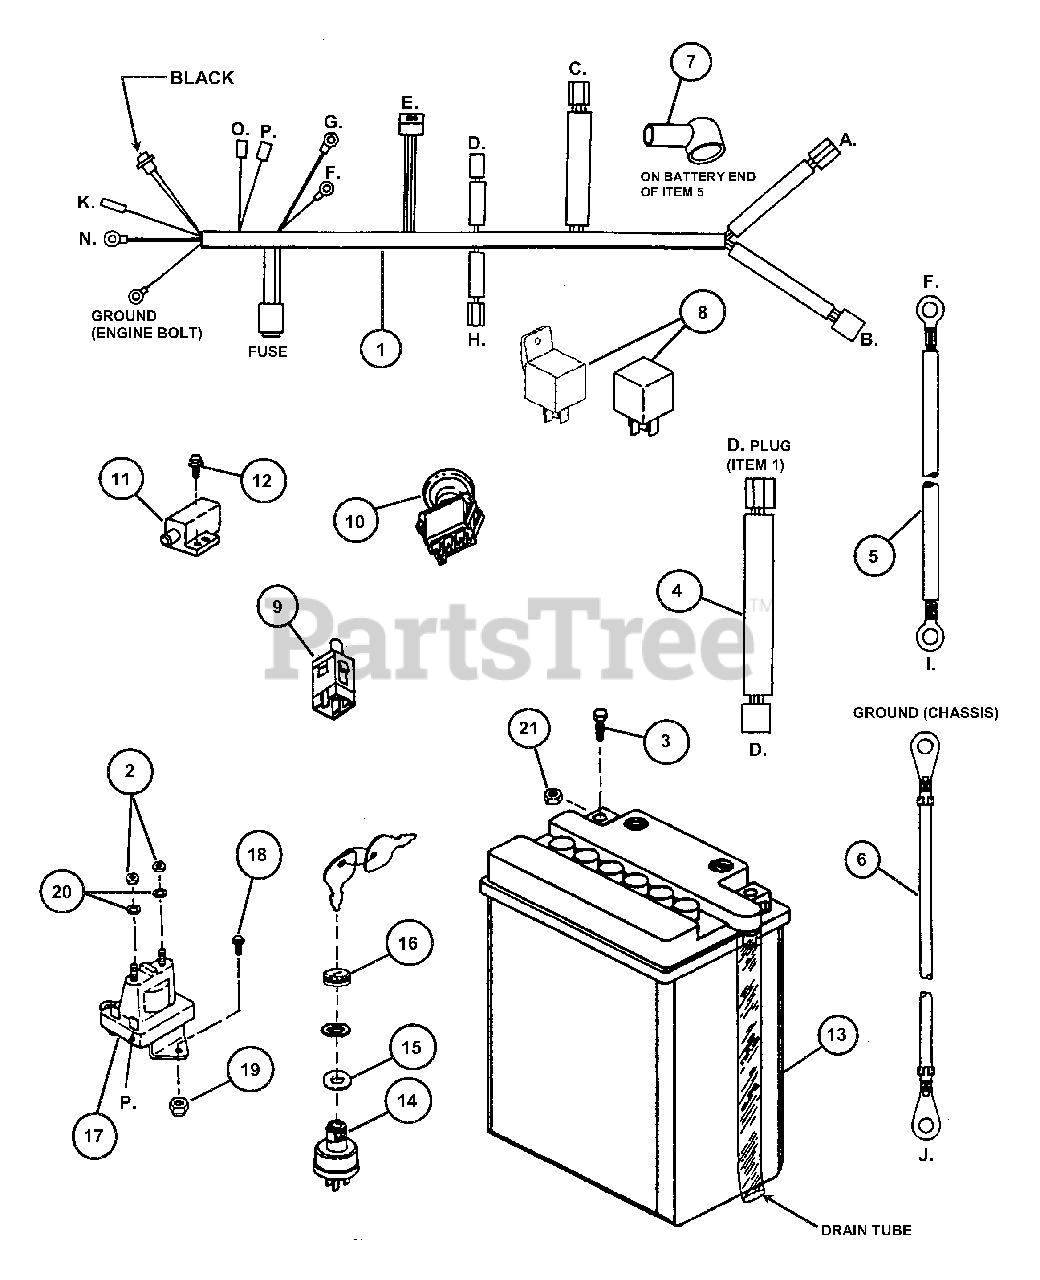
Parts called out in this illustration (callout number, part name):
1	WIRING HARNESS (14.5 & 15HP Briggs) (38" Deck Series 3 & 4)
2	NUT, 1/4-20 Hex Jam
3	SCREW, #10-24 x 1/2" Hex Head Cap
4	WIRING HARNESS, Warner Clutch (38" units)
5	WIRE, Positive, 13"
6	WIRE, Negative, 14"
7	COVER, Battery Cable
8	RELAY, Operator Presence Control
9	SWITCH, Seat (NC/NO)
10	SWITCH, PTO Electric Clutch
11	SWITCH, Park Break (NC/NO)
12	SCREW, #10-24 x 1/2" Hex Washer Self-Tap (Torx)
13	BATTERY, 12 Volt, 14 Amp, 190 Cold Cranking Amp
14	SWITCH, Ignition
16	BEZEL
17	SOLENOID, 12 Volt (was 18604)
18	SCREW, 1/4-20 x 1/2" Hex Head Cap, Grade 5
19	NUT, 1/4-20 Hex Flange Lock, Grade 5
20	WASHER, 1/4 Internal Tooth Lock
21	NUT, #10-24 Hex Twin "Whiz" Lock
